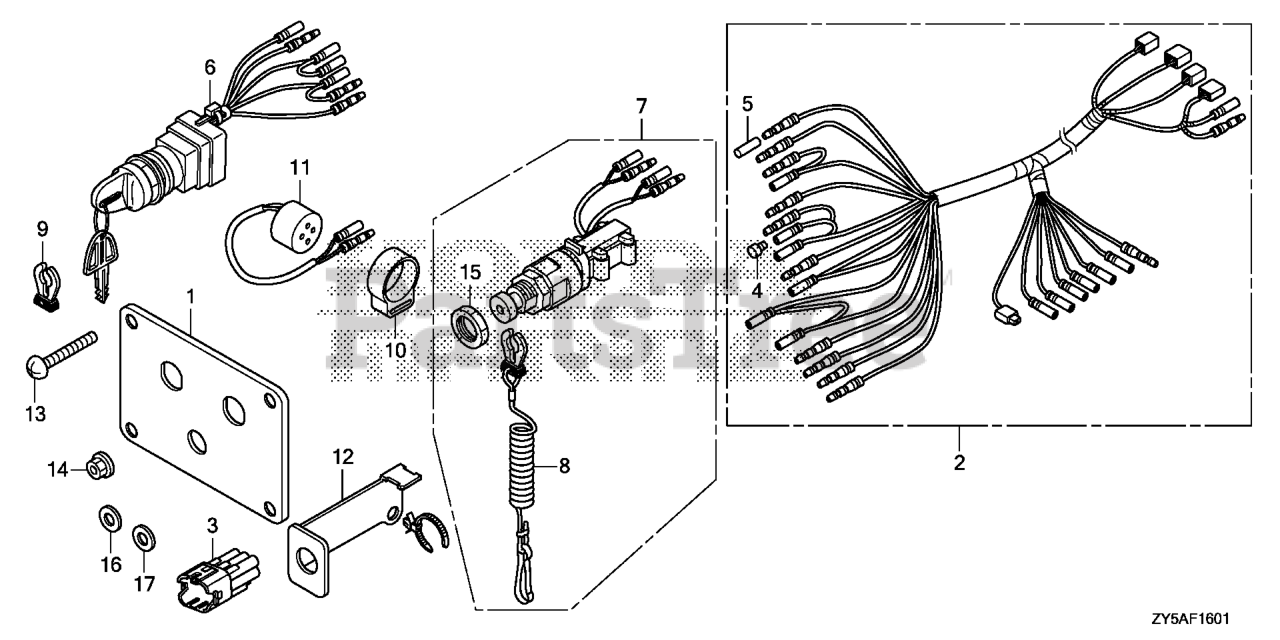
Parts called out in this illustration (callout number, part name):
1	PANEL, CONTROL (TWIN)
2	HARNESS ASSY., SWITCH PANEL
3	DUMMY, WATERPROOF CONNECTOR (GREEN)
4	PLUG, CONNECTOR (INNER) (TROLLING CONTROL)
5	PLUG, CONNECTOR (OUTER) (ENGINE NO.)
6	SWITCH ASSY., COMBINATION
7	SWITCH ASSY., EMERGENCY STOP (TWIN)
8	WIRE, EMERGENCY
9	CLIP, EMERGENCY LOCK
10	SUSPENSION, AUDIBLE PILOT
11	BUZZER, WARNING
13	SCREW, PAN (5X40) DUAL QTY = (8) (SINGLE)
14	NUT, FLANGE (5MM)
16	WASHER, PLAIN (5MM)
17	WASHER, SPRING (5MM)
